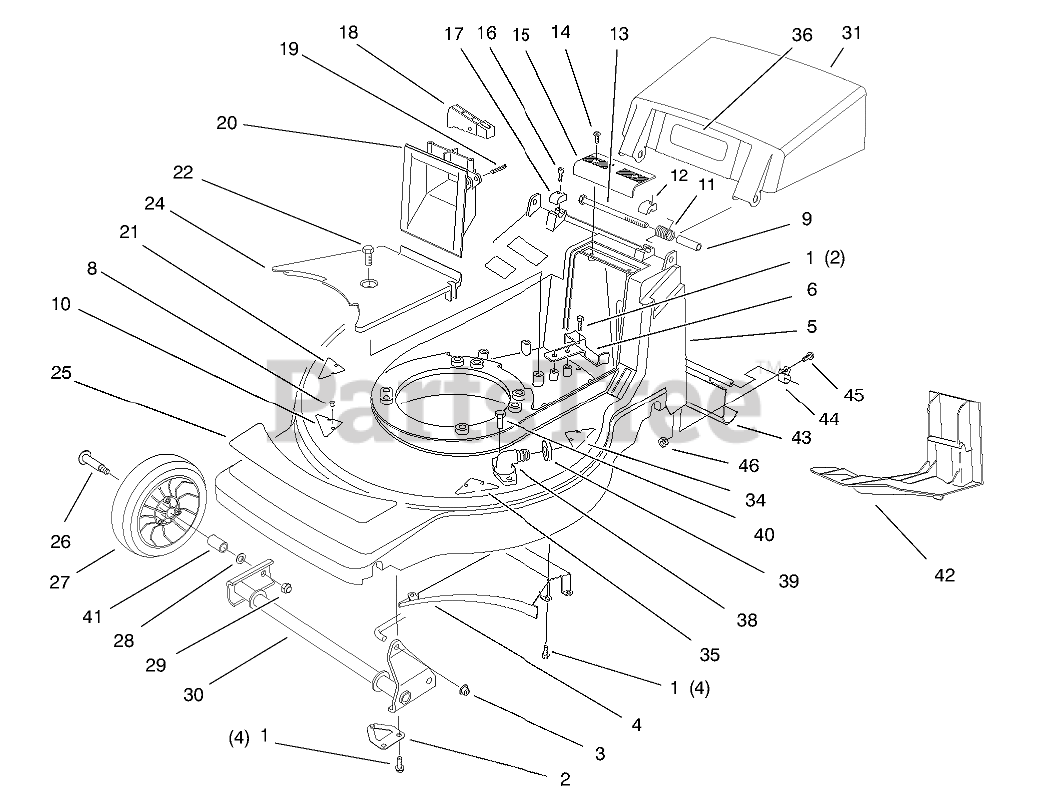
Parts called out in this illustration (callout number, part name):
1	SCREW-HWH
2	SHAFT RETAINER ASM
3	NUT-PUSH
4	Ramp-Discharge
5	Housing Assembly (Incl. Ref. # 8, 10, 21, 25, 34, 35, 38-40)
6	REAR BELT GUIDE
8	SCREW-PPH
9	SPACER-DOOR
10	KICKER
11	SPRING-DOOR
12	CAP-HINGE BOLT, LH
13	SCREW-HH
14	SCREW-PPH, PLASTITE
15	GRIP-UPPER
16	SCREW-HSH
17	CAP-HINGE BOLT, RH
18	TRIGGER - HOC
19	PIN-SPIRAL
20	GRIP - LOWER
21	KICKER
22	SCREW-HWHTF
24	BELT COVER
25	DECAL - DECK
26	Bolt-Wheel
27	Wheel & Tire Assembly (Incl. Ref. #41)
28	WASHER
29	NUT-HEX
30	FRONT PIVOT WA
31	Discharge Door Assembly (Incl. Ref. # 36)
34	KICKER
35	KICKER
36	DECAL-DANGER
38	FITTING-WASHOUT
39	O-RING
40	SCREW-HWH
41	BUSHING
42	DISCHARGE PLUG
43	SHIELD - TRAILING
44	HANGER - SHIELD
46	NUT-LOCK, NI
